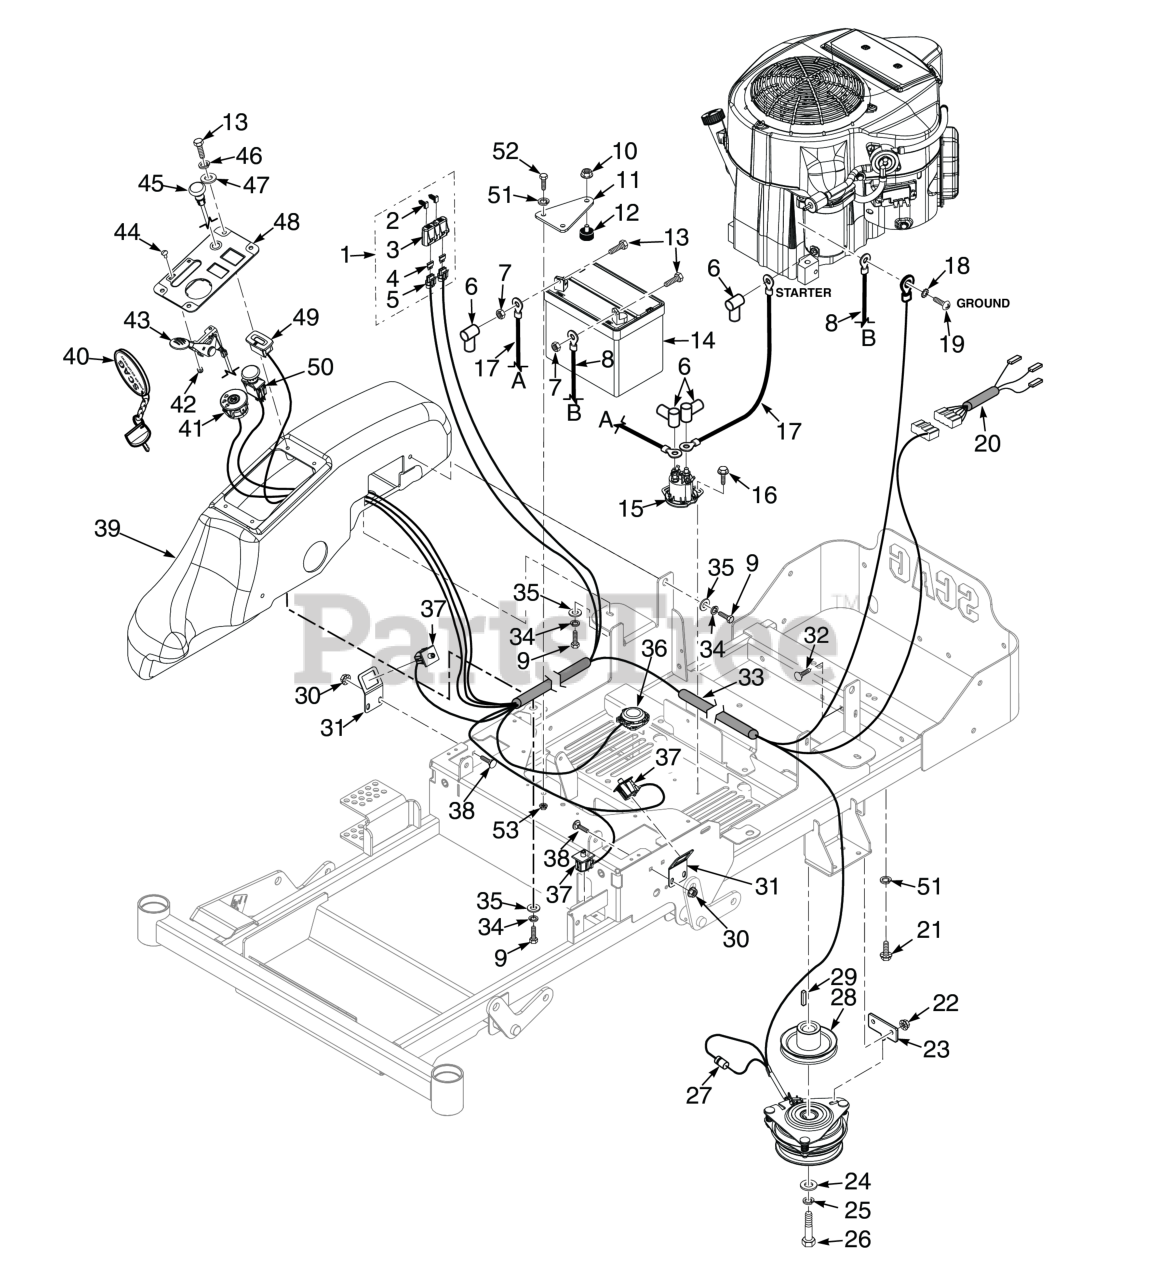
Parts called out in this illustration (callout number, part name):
1	Double Fuse Assy.
2	Clip, Fuse Holder
3	Cover, Sealed Double
4	FUSE, 20 AMP BLADE TYPE AUTOMOTIVE
5	Fuse Holder Assembly
6	RUBBER BOOT
7	Nut, 1/4 - 20 Hex
8	Battery Cable, 31-1/2" Black (25KA, 26DFI, 31DFI) - Kawasaki
9	BOLT, SERRATED FLANGE HEX HEAD 5/16-18 X 3/4"
10	Nut, Serrated Flange 5/16-18 (Right Front Engine Mounting, Briggs and Kohler Only)
11	Battery Hold Down
12	Bumper, Rubber 5/16-18 x 5/8"
13	Bolt, Hex Head 1/4-20 x .5" Battery, (Not Available Through Scag)
14	Battery, 12v - 230CCA
15	Solenoid, Sealed (Briggs & Stratton)
16	Screw, Self-Tapping 1/4-20 x 3/4
17	Battery Cable, 18" Red w/Braid (25KA, 26DFI, 31DFI) - Kawasaki
18	Lockwasher, 5/16" Ext. Tooth (Kohler x1)
19	Bolt, Hex Head M8 - 1.25 x 16 (48V / 52V)
21	Bolt, Hex Head 3/8-16 x 1-1/4", Kawasaki FX / FT & FT-EFI
22	Nut, Flange Head Elastic Stop 5/16-18
23	Plate, Anti-Rotation
24	Flatwasher, 7/16-.469 x 1.75 x .25 (48, 52)
25	Lockwasher, 7/16� Spring
26	Bolt, Hex Head 7/16-20 x 3¼" w/Patch
27	Diode, 600V 6 Amp
28	Pulley, 4-1/2" - 1" Bore
29	Key, 1/4 x 1/4 x 1.25" Pulley Mtg.
30	Nut, Flanged Elastic Stop 1/4-20
31	Bracket, Switch
32	Bolt, 5/16-18 x .75 RHSN Carriage
33	Wire Harness
34	Lockwasher, 5/16 (.317 x .586 x .078) Helical Spring
35	Flatwasher, 5/16-.375 x .875 x .083 (35BV & 37BV-EFI)
36	Switch, Double Pole - Twist
37	Switch, Double Pole - Plunger
38	Serr. Fl. Hex Head CPSCR, 1/4-20 x 3/4"
39	Console Tank w/Decals, SZL-36
40	Key, Assembly w/Fob
41	Ignition Switch
42	Nut, Elastic Stop #10-24
43	Throttle Control, Kawasaki
44	Bolt, Carriage #10-24 x 1/2"
45	Choke Control, Kawasaki
46	Lockwasher, 1/4� Spring
47	Flatwasher, 1/4" (.312 x .750 x .065")
48	Instrument Panel w/Decal, SZL-36
49	Hour Meter, Inductive
50	Switch, PTO - 10 Amp
51	Lockwasher, 3/8" Spring, Kawasaki FX / FT & FT-EFI / B&S 32BV
52	Bolt, Hex Head, 3/8-16 x 1 Gr. 5
53	Threaded insert, Hex Head (Pressed)
